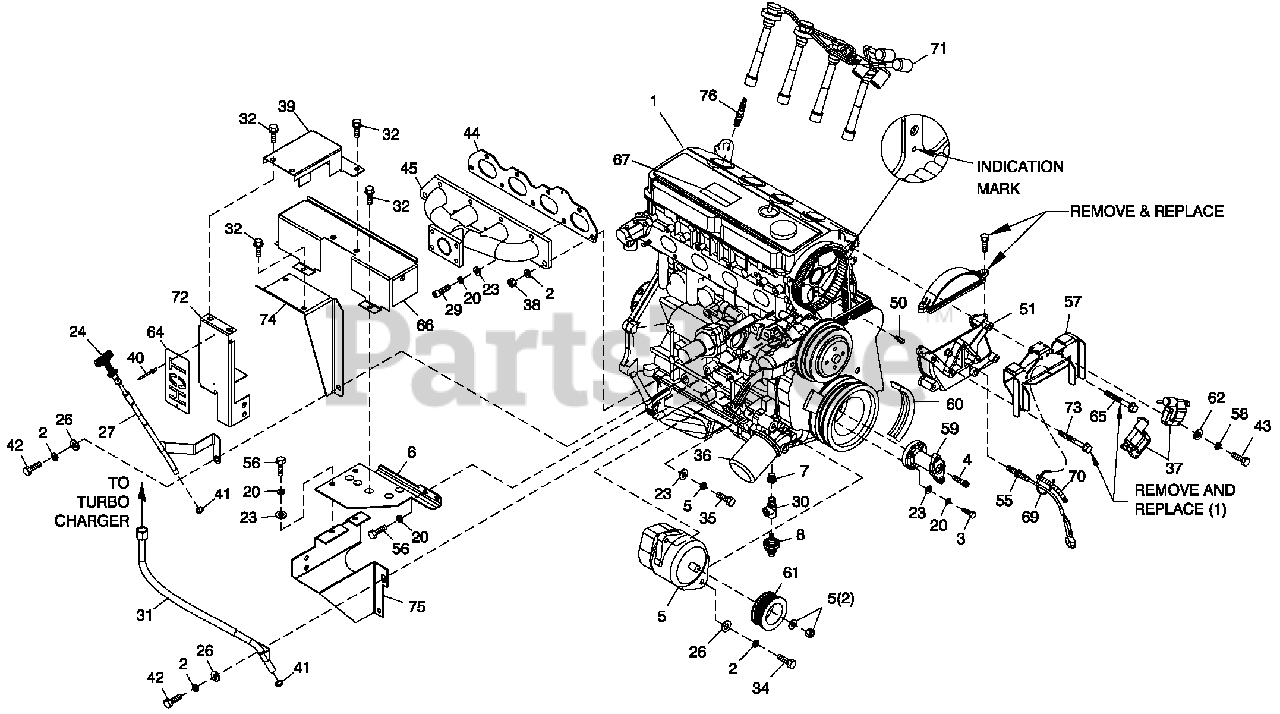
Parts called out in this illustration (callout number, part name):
1	ENGINE 2 .4 L G 2
2	WASHER LOCK M10
3	SCREW HHC M 8-1.25X 35 G8.8
4	SCREW SHC M14-1.5 X 35 G10.9
5	ALTERNATOR DC W/OUT PULLEY
7	ADAPTOR 1/8N PTF TO 1/8BS PT
8	SWITCH OIL PRESSURE 10 PSI 2 POL (R- PANEL)
20	WASHER LOCK M8-5/16
23	WASHER FLAT 5/16-M8 ZINC
24	ASSY DIPSTIC KW/TEXT GTH-530
26	WASHER FLAT 3/8-M10 ZINC
31	TUBE TURBO OIL RETURN G2 36KW
32	SCREW HHTT M 6-1.0X 12ZIN C
34	SCREW HHC M 10-1.5X 60 G8.8
36	FILTER 1.5 L /2 .4L G 2 OIL
37	COIL-2.4 LG 2 IGNITION
38	NUT HEX M10-1.25 GEYEL CHR
39	HEAT SHEILD INNER 2.4L G2 36K
40	RIVET POP .1 2 5 X 0 .3 3 7 STEEL
41	O-RING SIZE 9.0MM X 2.0MM NITR
42	SCREW HHC M10-1.25 X 20 C8.8
43	SCREW HHM # 1 0 -3 2 X 1 -1 /4
44	GASKET EXHAUSTM ANIFOLD
45	MANF ASSY (TUBULAR) 2.4L G2
50	CAM SENSOR PIN ASSY
51	COVER CAM GEAR G2 REWORKED
55	VR SENSOR ASSY 3/8-24 LOW SENS
56	SCREW HHC M 8-1.25X 16 C8.8
57	BRACKET ASM -2.4L COIL G2
58	WASHER LOC K #10
59	ADAPTE R 2.4L CRANKSHAFT MACH
60	BELT SERPENTINE 37.0" (1800 RPM)
61	PULLEY 69 OD DC ALTERNATOR (1800 RPM)
62	WASHER FLAT #10 ZINC
64	PLATE "HOT "
65	SCREW HHC M 8 -1 .2 5 X 7 0 G 8 .8
66	SHIELD-M ANIFOLD 2.4L G2 36KW
67	DECAL EMISSION CTRL INFO 2.4L
69	TIE WRAP UL 7.4"X .19" BLK
70	CONDUIT FLEX .25"ID
71	SPARK PLUG WIRE SET 2.4L G2 IG
72	HEAT SHIELD OUTER 2.4L G 2 36K
73	SCREW HHC M 8 -1 .2 5 X 6 5 C 8 .8
74	BRKT-EXH MANF 2.4L 36KW
75	LWR BRKT ASM HT SHIELD G2 36KW
76	PLUGS PARK
